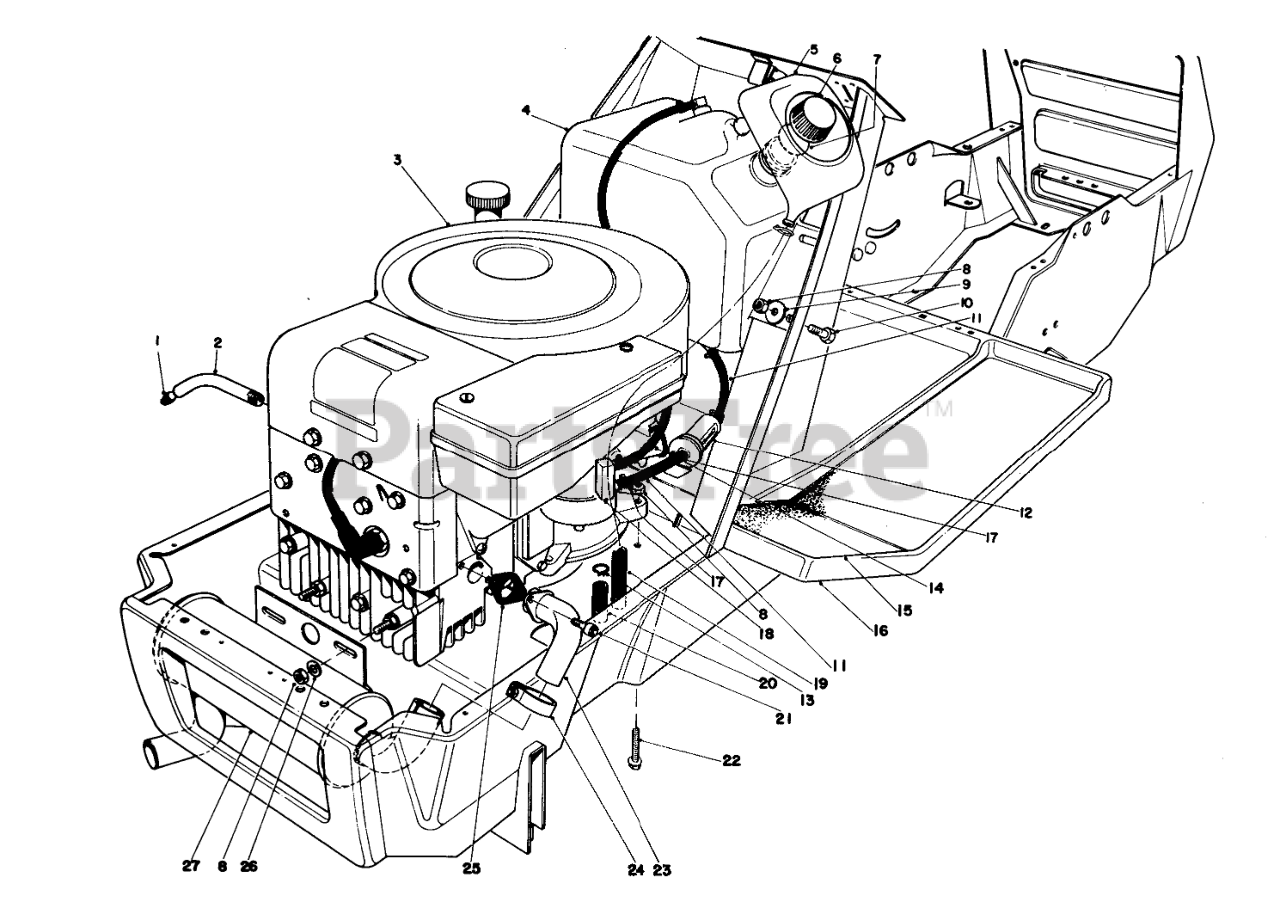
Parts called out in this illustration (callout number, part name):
1	PLUG-PIPE, SQH
2	OIL DRAIN TUBE
3	Engine
4	Gas Tank Assembly (Inch. Ref. #5)
5	Funnel Overflow
6	Gas Cap Assembly (Incl. Ref. #7)
7	Gasket Gas Cap
8	NUT-LOCK, CONE
9	WASHER
10	SCREW-HH
11	GAS HOSE
12	Fuel Filter
13	HOSE CLAMP
14	Gas Return Hose
15	LH FOOT TREAD
16	Frame
17	CLAMP-HOSE
18	Fitting Carburetor
19	FUNNEL HOSE
20	CARB DRAIN HOSE
21	SCREW-HSH
22	SCREW-HH
23	10 HP EXHAUST PIPE WA
24	MUFFLER CLAMP
25	Exhaust Gasket
26	WASHER-PLAIN
27	EXHAUST MUFFLER 10 HP
